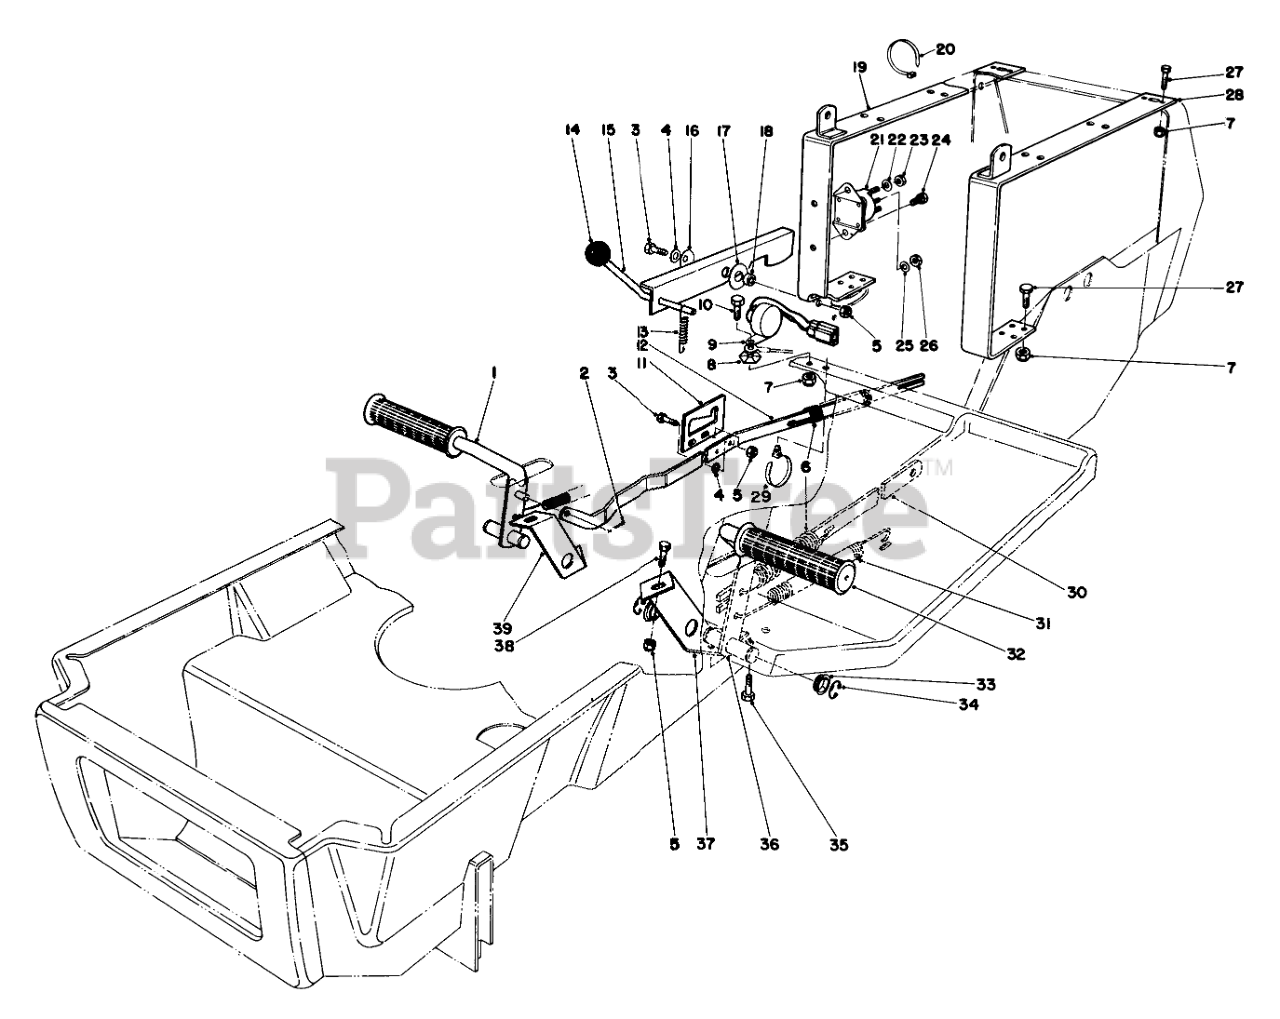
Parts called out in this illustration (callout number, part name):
1	BRAKE PEDAL WA BO
2	PIN-COTTER
3	SCREW-HH
4	WASHER-PLAIN
5	NUT-LOCK, CONE
6	EXT SPRING O
7	NUT-LOCK, CONE
8	Washer
9	Module Interlock
10	SCREW-HH
11	LATCH PLT-BRAKE ROD
12	LINK BRAKE ROD WAB
13	CONT ROD SPRING 0
15	PARKING BRAKE WA B
16	WASHER-BELLEVILLE
17	WASHER-PLASTIC
18	SPACER
19	RR BODY STRAP WA B
20	TIE-CABLE
21	SOLENOID
22	WASHER-LOCK
23	NUT-JAM, BRASS
24	SCREW-HWH
25	NUT-HEX
26	WASHER-LOCK
27	SCREW-HH
28	LH RR BODY STRAP WA B
29	TIE-MOUNT, PUSH
30	CLUTCH ROD LINK B
31	SPRING-EXTENSION
32	FOOT PAD
33	Nyliner
34	E-RING
35	SCREW-HWHTF
36	CLUTCH PEDAL WA BO
37	LH PEDAL SUPT B
38	SCREW-HH
39	RH PEDAL SUPT B
